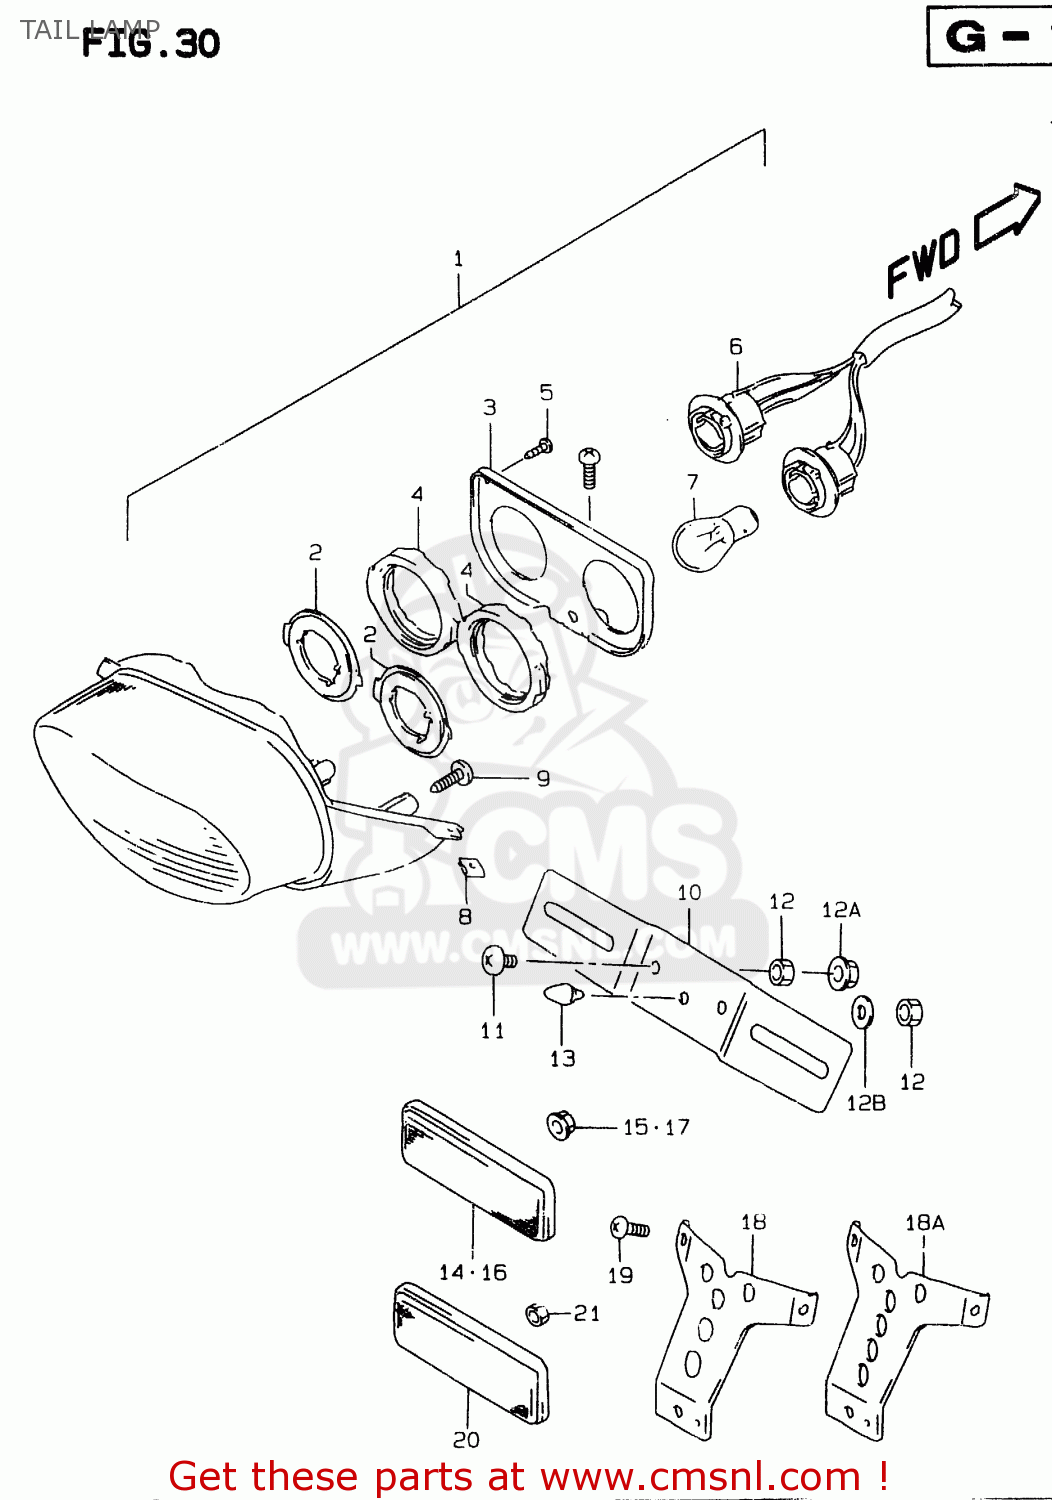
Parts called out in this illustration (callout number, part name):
1	LAMP ASSY,RR COMBINATION
2	PLATE NO.1
3	PLATE NO.2
4	CUSHION
5	SCREW
6	SOCKET & CORD
7	BULB(12V21/5W)
8	NUT
9	SCREW
10	PLATE,RR LICENSE
11	SCREW 6X12
12	NUT 6MM
12A	NUT
12B	WASHER(6.5X20X1.2)
13	CUSHION
14	REFLECTOR ASSY,RR
15	NUT
16	REFLECTOR ASSY,RR
17	NUT
18	BRACKET,RR REFLECTOR
18A	BRACKET,RR REFLECTOR
19	SCREW(6X12)
20	REFLEX REFLECTOR,FR SIDE
21	NUT
